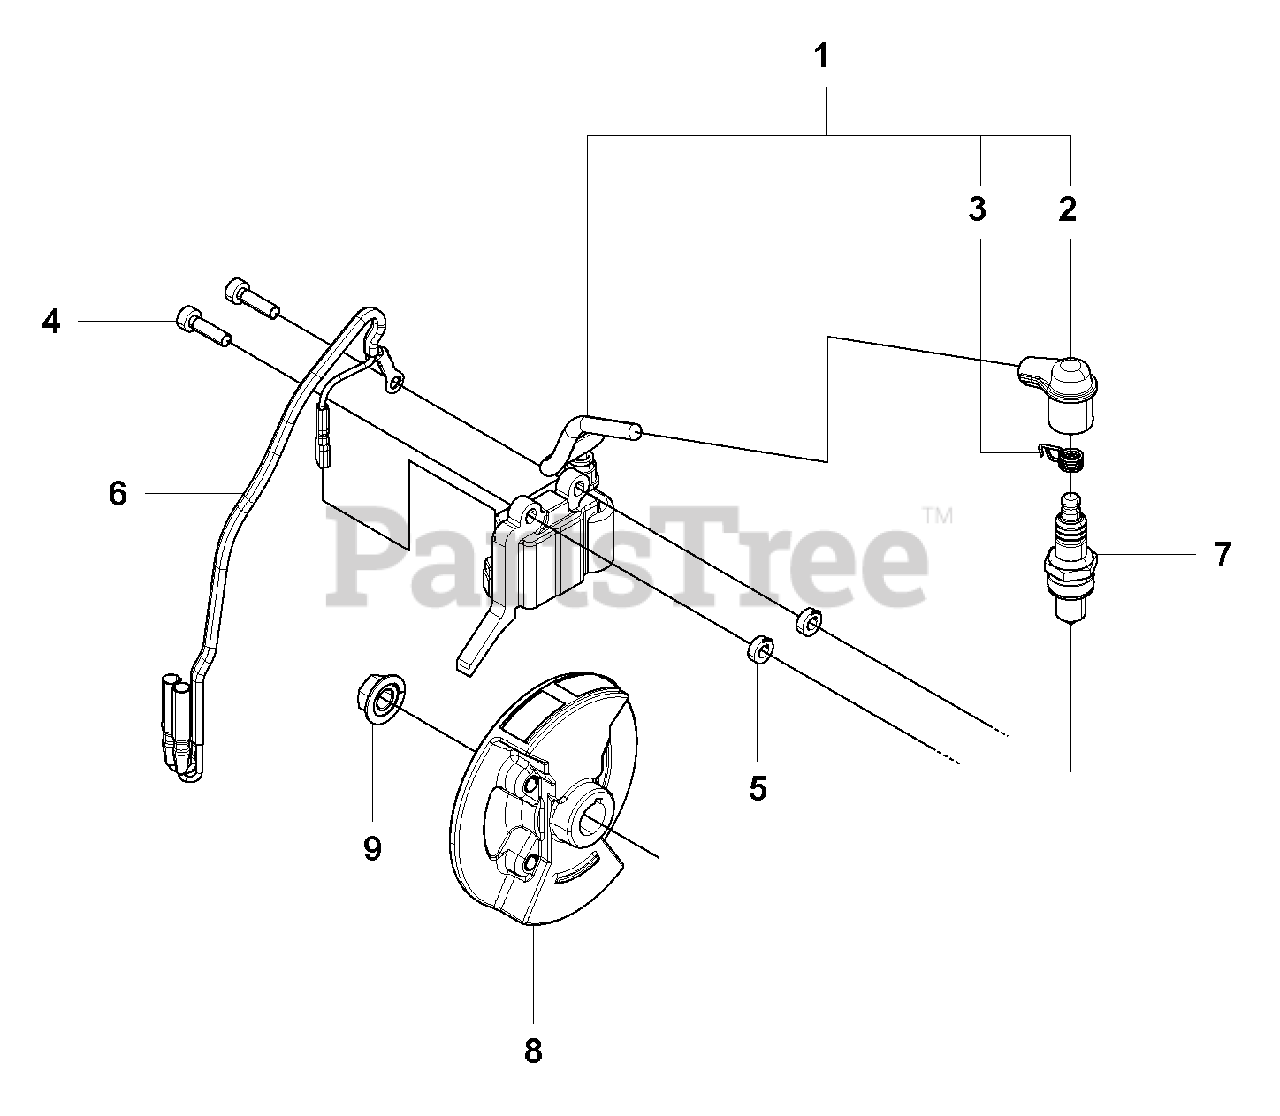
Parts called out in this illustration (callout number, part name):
1	COIL A
2	CAP
3	SPRING
4	BOLT
6	CORD-COMPL.
7	SPARKPLUG NGK CMR7H
9	NUT
